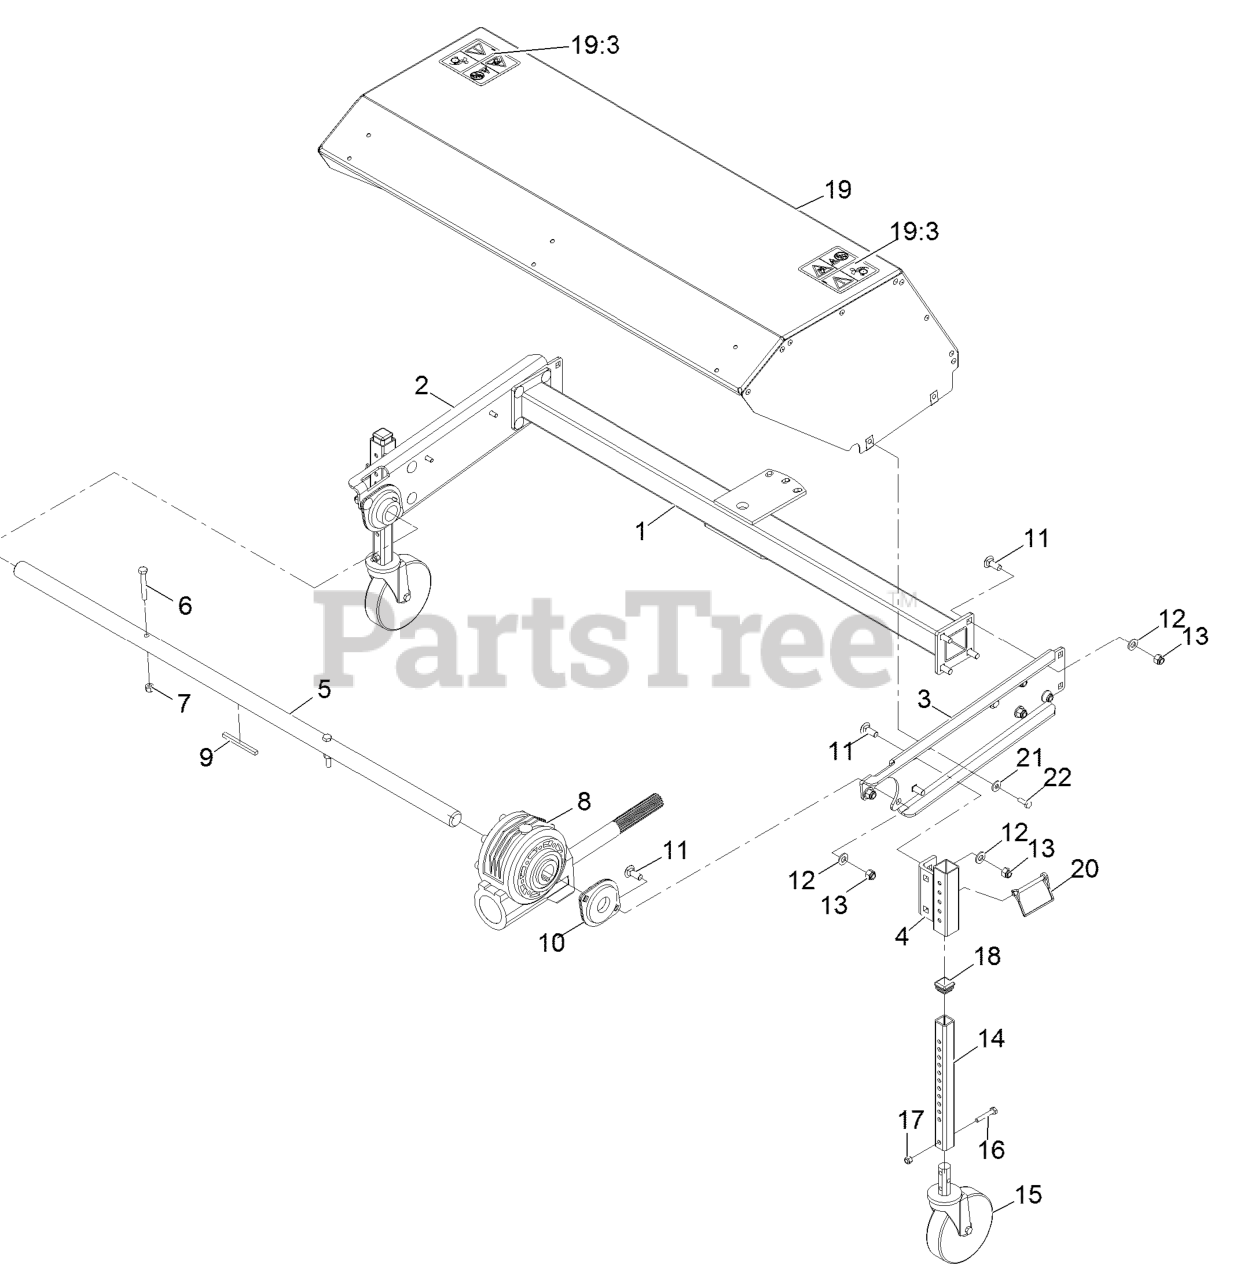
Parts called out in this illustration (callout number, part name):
2	Arm-Right
3	Arm-Left
4	Caster-Bracket
6	Screw-HH 5/16-18 X 2 1/4
7	Nut-Nyloc 5/16-18
8	Gearbox-Worm
9	Key-Straight
10	Bearing-Flange
11	Bolt-Carriage 3/8-16 X 1
12	Washer-3/8 SAE
13	Nut-Nyloc 3/8-16
14	Tube-Square, Height Adjust
15	Caster-Wheel
16	Screw-HH 1/4-20 X 1 1/2
17	Nut-Nyloc 1/4-20
19	Broom Hood ASM
19:3	Decal-Warning
20	Pin-Wire, Lock
21	Washer-1/4 Std
22	Screw-HH 1/4-20 X 3/4
